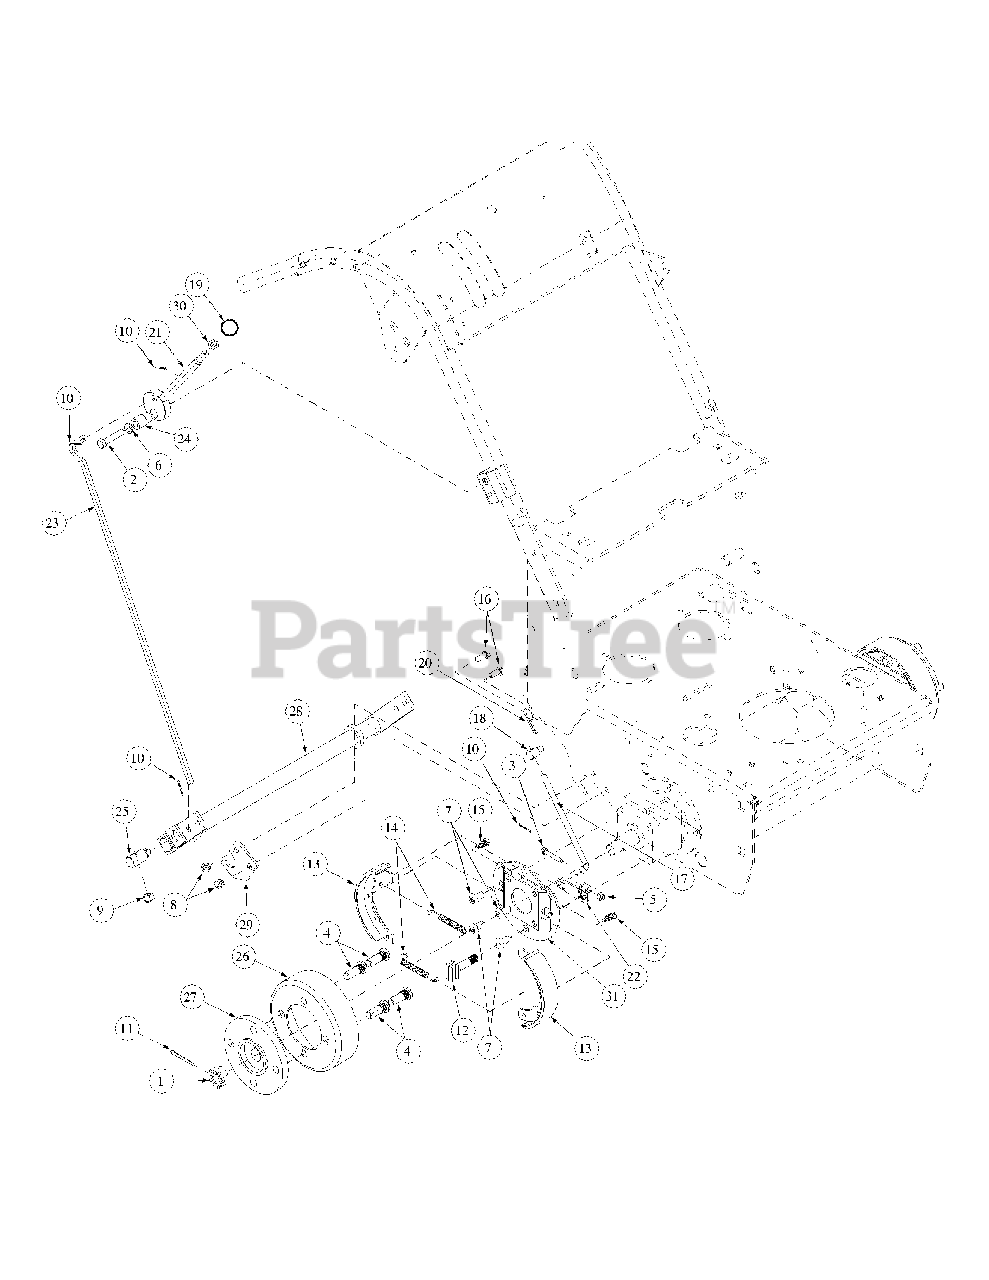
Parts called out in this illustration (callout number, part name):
1	Nut, Castle, 3/4-16
2	Capscrew, 3/8-16 x 1" Grade 5 Zinc
3	Cap Screw, 1/4-20 x 1.50, Grade 5
4	Bolt, Wheel, 1/2-20 x 1-3/8
5	Lock Nut, Nylon Insert, 1/4-20 Grade A
6	Lock Washer, 3/8 Zinc
7	Capscrew, Socket Button Hd., 3/8-16 x 3/4 Zinc
8	Nut, 5/16-18, Nylock
9	Nut, Nylon Insert, 3/8-16 Grade A
10	Cotter Pin, 3/32 x 3/4, Zinc
11	Cotter Pin, 5/32 x 1-1/2 Zinc
12	Brake Cam, Actuating
13	Brake Shoe w/Lining, 6 x 1-1/4
14	Brake Spring, Tension
15	Brake Spring, Anti-Vibration
16	Cap Screw, 5/16-18 x 3/4, Grade 5
17	Brake Rod
18	Swivel Joint
19	Red Knob, Shift w/Insert
20	Hair Pin 3/8"-1/2"
21	Lever Assembly, Brake
22	Brake Clamp, Control Assembly Hydro
23	Rod, Long Brake, Hydro WB
24	Pivot Spacer, Hydro WB
25	Brake Pull Joint
26	Brake Drum
27	Hub, Wheel Motor
28	Brake Pivot Shaft Assembly
29	Pivot Mount, Brake
30	Nut, 3/8-16, Jam, Grade 2
31	Brake Backing Plate
